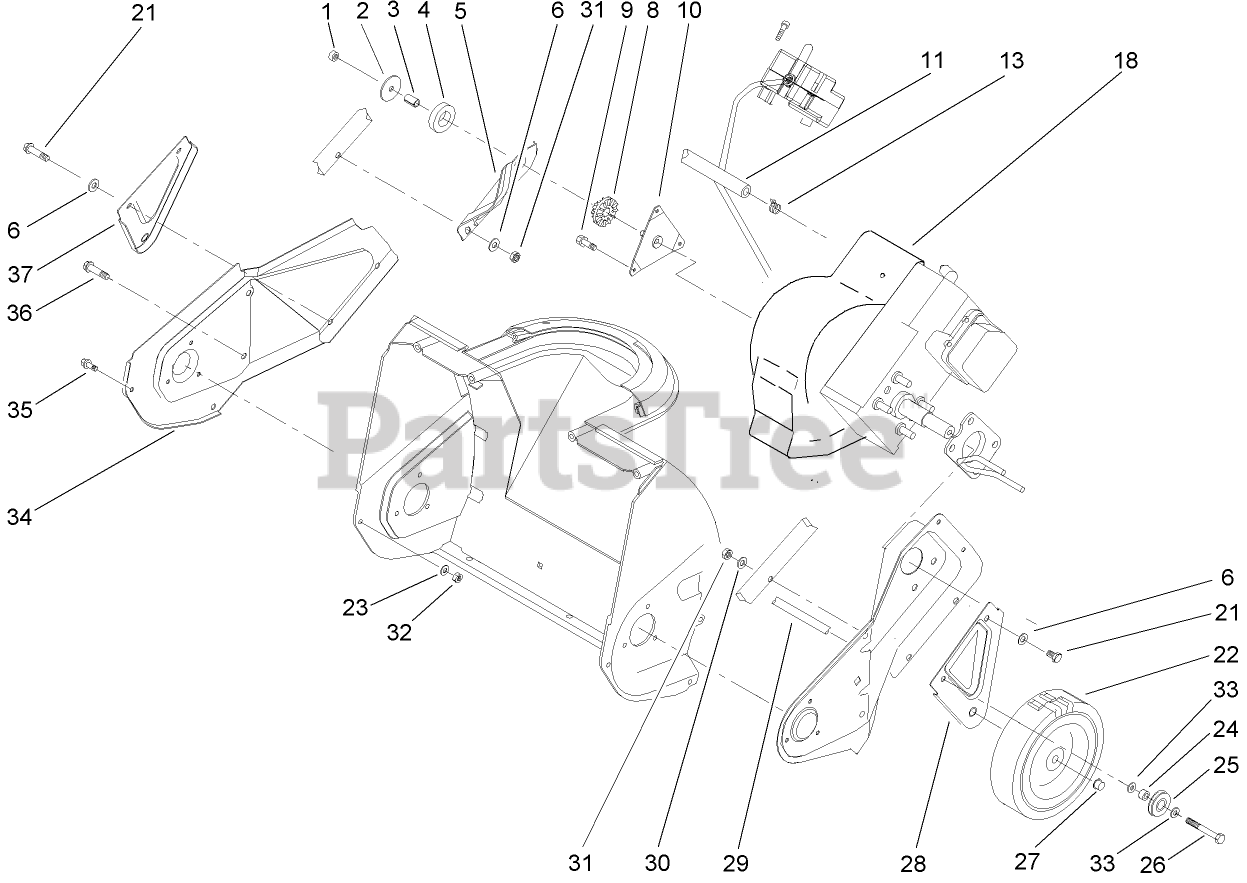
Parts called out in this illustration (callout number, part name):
1	NUT-LOCK, NI
3	SPACER-TUBULAR
4	RING-ISOLATOR
5	BRACKET-SUPPORT, ENGINE
6	WASHER-FLAT
8	BUSHING-ISOLATOR
9	SCREW
10	BRACKET AND STUD ASM
11	LINE-GAS
13	CLAMP-HOSE
18	Loose Parts Package
21	SCREW-HH
22	WHEEL
23	WASHER-FLAT
24	SPACER-BLADE, ROTOR
25	CABLE-PULLEY
26	SCREW-HH
27	NUT-PUSH
28	BRACKET-WHEEL, LH
29	AXLE SHAFT
30	WASHER
31	NUT-LOCK, NI
32	NUT-LOCK, NI
33	WASHER-FLAT
34	PLATE-SIDE, RH
36	SCREW-PLASTIC
37	BRACKET-WHEEL, RH
